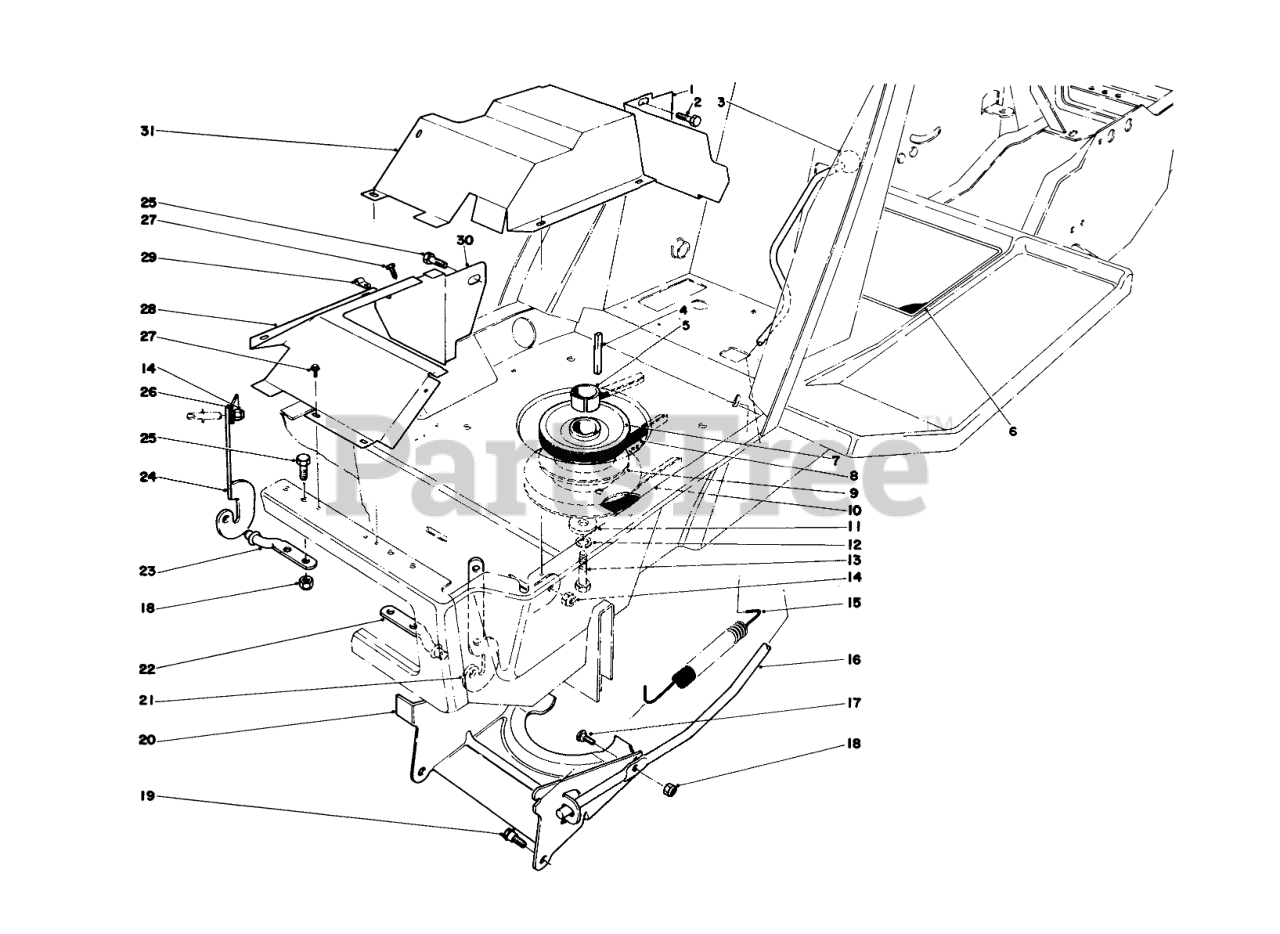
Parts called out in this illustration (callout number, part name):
1	EXH SHIELD SUPT B
2	SCREW-HH
3	Knob
4	KEY-SQUARE
5	PULLEY SPACER
6	OPERATION DECAL
7	Sheave
8	V BELT
9	Clutch & Brake Deck
10	V BELT
11	WASHER
12	WASHER-LOCK
13	SCREW-HH
15	TRACTION SPRING
16	Engagement Lever
17	Bolt
18	NUT-LOCK, CONE
19	SCREW-SHOULDER
20	CLUTCH ACTUATOR R
21	L.H. HINGE BRACKET
22	LH HOOD HINGE PIN
23	RH HOOD HINGE PIN
24	RH HINGE BRKT
25	SCREW-HH
26	SCREEN SUPT BRKT
27	SCREW-HWHTF
28	Heat Shield
29	CABLE CLAMP
30	Support Heat Shield
31	HEAT SHIELD WA B
